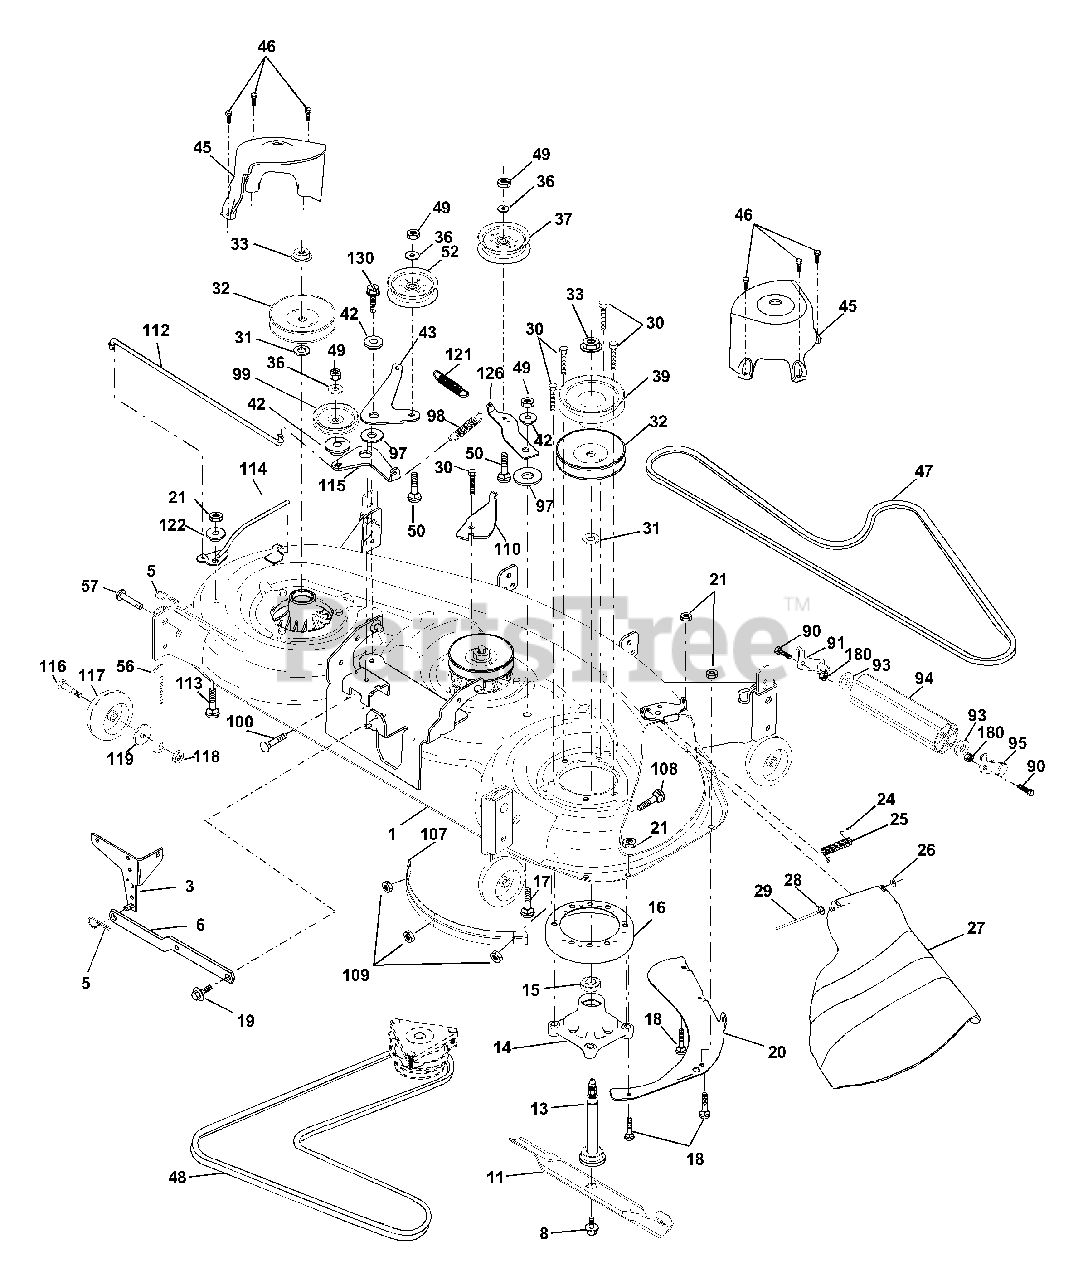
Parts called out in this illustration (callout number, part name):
1	Deck Weldment Mower 48
3	Bracket Asm., Sway Bar
5	Retainer Spring
6	Arm, Suspension, Rear (Sway Bar)
8	Bolt 7/16 Asm. Blade
11	Blade
13	Shaft Asm. w/Lower Bearing
14	Housing Mandrel 48"
15	Bearing, Ball, Mandrel
16	Stripper Mandrel Deck
17	Bolt RDHD Sq Neck 3/8-16x1.25
18	Bolt, Carriage 5/16-18 x 5/8
19	Bolt, Hex Hd, Shoulder 5/16-18
20	Baffle, Vortex Mower
21	Nut, Crownlock 5/16-18 UNC
24	Cap, Sleeve
25	Spring, Torsion
27	Deflector Shield
28	Washer 11/32 x 5/8 x 16 Ga.
29	Rod, Hinge
30	Screw, Thdroll Washer Head
31	Washer, Spacer Mower Vented
32	Pulley, Mandrel
33	Nut, Flg. Top Lock Cntr. 9/16
36	Washer 13/32 x 13/16 x 16 Ga.
37	Pulley, Idler, Flat
39	Pulley, Idler, Driven
42	Spacer, Retainer
43	Arm, Idler Secondary
45	Cover, Mandrel Deck
46	Screw, Thdroll. 1/4-20 x 5/8
47	V-Belt, Mower, Secondary
48	V-Belt, Mower, Primary
49	Nut, Crownlock 3/8-16 UNC
50	Bolt, Carr. 3/8-16 x 1-1/2 Gr. 5
52	Pulley Idler Flat
56	Bar Pnt Adj.
57	Pin Head Rivet
90	Bolt, Hex Hd 5/16-18 x 1
91	Bracket, Asm Noseroller, RH
93	Washer 17/32 x 7/8 x 16
94	Noseroller
95	Bracket, Asm Noseroller LH
97	Washer Hardened
98	Spring Primary Drive
99	Pulley Idler "V"
100	Bolt RDHD Sqnk 3/8-16 UNC x 2
107	Baffle Vac Edge Mower
108	Bolt Carr.
109	Nut Crownlock 1/4-20
110	Arm Spring Secondary
112	Link Tension Relief Lever
113	Bolt Carr. 5/16-18 x 1
114	Tension Asm. Relief Lever
115	Arm Spring Tension Relief
116	Bolt, Shoulder
117	Gauge Wheel
118	Nut, Centerlock 3/8-16 UNC
119	Washer 3/8 x 7/8 x 14 Ga.
121	Spring Secondary Drive
122	Bushing Pivot Tension Relief
126	Arm, Idler, Primary Deck
130	Screw 3/8-16 x 1.0
180	Nut Lock Hx w/Ins. 5/16-18
